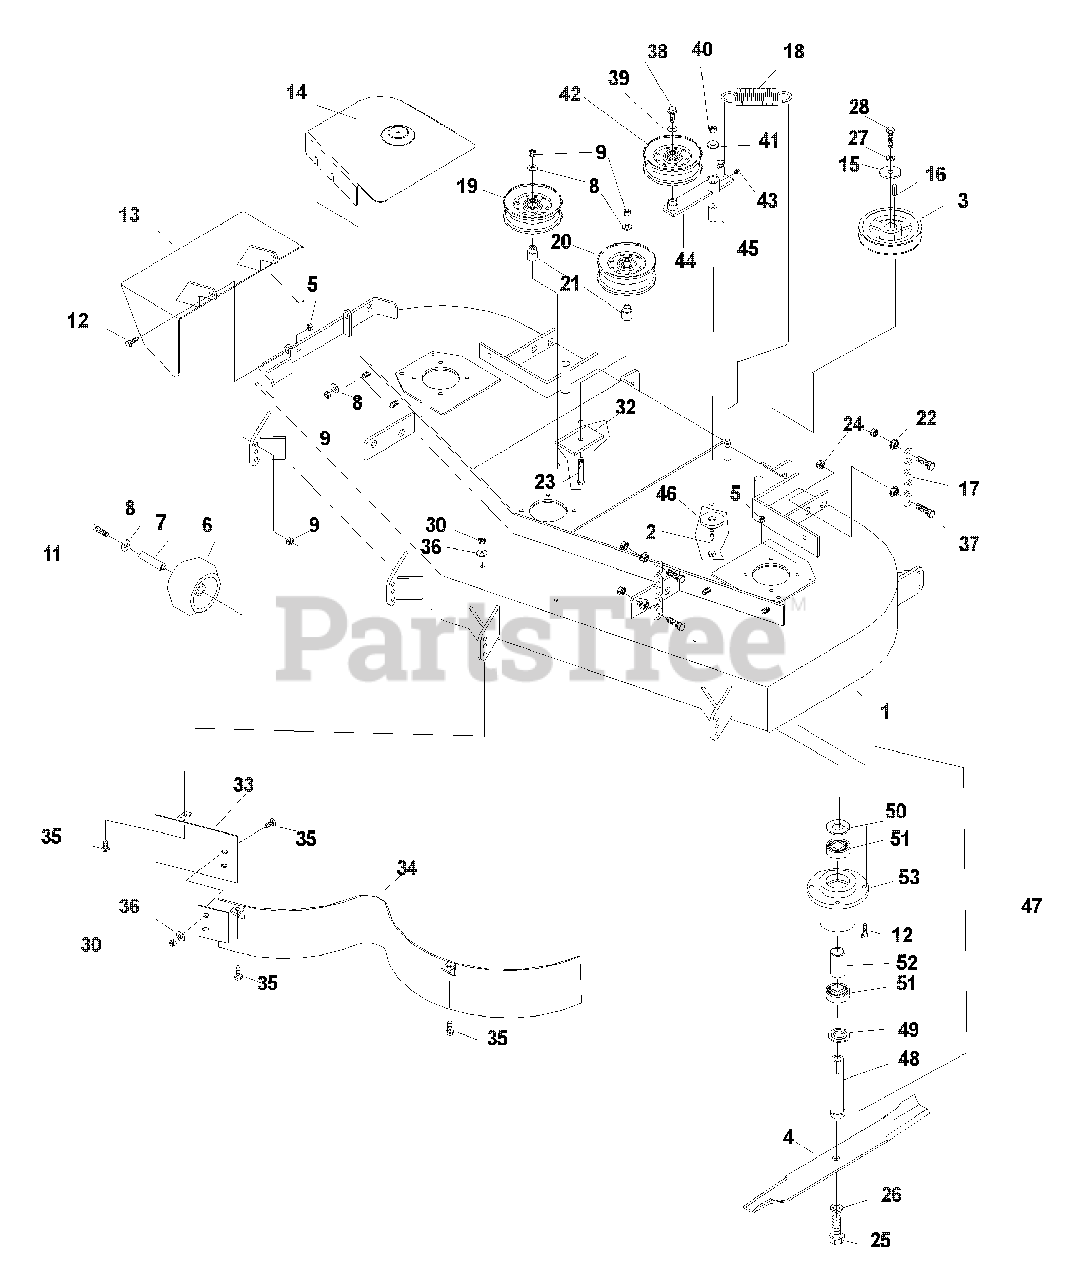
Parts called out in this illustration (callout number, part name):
1	DECK W/DECALS
2	HCS 1/2C X 3 1/4, GR. 5
4	BLADE, 18"
5	NUT 5/16C, NYLOC
8	WASHER 3/8, STD
9	NUT 3/8C, NYLOC
11	HSC 3/8C X 3 1/2
12	HCS 5/16C X 1 1/4
13	DISCRGE CHUTE
14	BELT SHEILD, RT
15	HEAVY WASHER
16	KEY, 1/4 SQ. X 1 1/8
17	LIFT CHAIN
19	IDLER PULLEY 1.31
20	IDLER PULLEY 1.62
21	IDLER BUSHINGS
22	NUT 7/16C, WHIZ
23	HCS 3/8C X 2 3/4
24	NUT, 7/16C, CENTERLOCK
25	HCS 5/8F X 1 1/4
27	LOCKWASHER, 7/16
28	HCS 7/16F X 1 1/2
30	NUT 5/16C, CENTERLOCK
32	PAD
33	CENTER BAFFLE
34	MAIN BAFFLE
35	RHSNB 5/16C X 5/8
36	FLAT WASHER, 5/16
37	HCS 7/16C X 1 1/2
38	HCS 3/8C X 1 SER.
39	FLAT WASHER 3/8
40	NUT 1/2C, NYLOC
41	FLAT WASHER 1/2
42	IDLER PULLEY
43	ZERK
45	PIVOT BUSHING
46	SUPPORT WASHER
47	CUTTER HOUSING, COMPLETE
49	COMBO SPACER
50	MACHINERY BUSHING, 18 GA
51	BEARING
